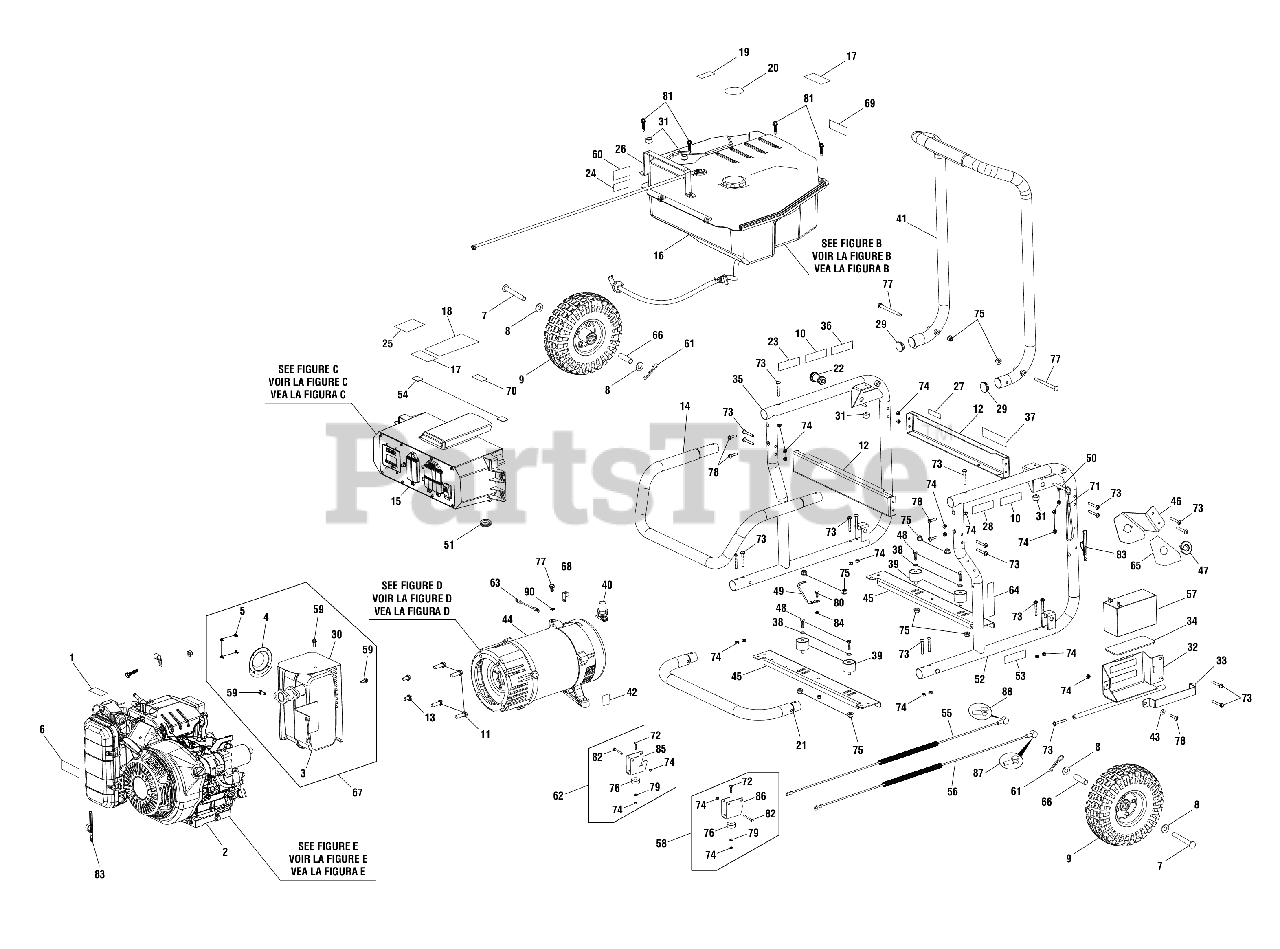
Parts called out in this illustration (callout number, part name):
1	Choke Label
2	Engine
3	Muffler w/Brackets
4	Spark Arrester Screen
5	Screw (8-32 x 3/8 in., Pan Hd.)
6	EMC label
8	Washer (1/2 in.)
9	Wheel (10 in. x 3 in.)
10	LABEL, ZERO GRAVITY
11	Bolt, Wiz (3/8-18 x 1-1/4 in.)
12	CROSSMEMBER, FUEL TANK
13	Bolt (5/16-24 x 0.6 in., Hex Hd.)
14	FRONT TUBE, TOP RIDGID
15	Control Panel Assembly (See Figure C)
16	Fuel Tank (See Figure B)
17	LABEL, LOGO RIDGID
18	LABEL, PERFORMANCE 7000 WATT
19	No E85 Label
20	Fuel Stabilizer Label
21	FRONT TUBE, BOTTOM
22	RELEASE PIN CM80034
23	Fire Distance Label (Eng/Sp)
24	Hot Surface and Exhaust Label
25	CPSC Danger Label
26	BRACKET, WRAPPER BOX SUPPORT
27	LABEL, CLICK/CALL/SCAN RIDGID
28	Risk of Fire Danger Label
29	End Cap (Handle)
30	Heat Shield
31	Rubber Bumper
32	BATTERY BOX ASSEMBLY, SMALL
33	Battery Hold Down Bracket Assembly
34	Gasket (Battery Hold Down Bracket)
35	RIGHT FRAME ASSEMBLY
36	Quick Release Pin Label
37	Ground Warning Label
38	Lock Washer (OD14.8 x ID8.5 x 1t)
39	Isolator Generation 7
40	Rubber Sleeve
41	HANDLE ASSY W/ CAPS
42	Ground Label Icon
43	Data Label
44	ASSEMBLY, GENHEAD 7.0kW, Al, <6% THD
45	CROSSMEMBER, ENGINE/GENHEAD
46	BRACKET, FUEL VALVE, RIDGID
47	Fuel Valve Bezel
48	Bolt (M8 x 1.25 in., Hex Hd.)
49	Ground Wire Assembly
50	Release Pin (5/16 x 2 in.)
51	GROMMET 16mm ID
52	LEFT FRAME ASSEMBLY
53	Engine Lubricant Label
54	RUBBER ISOLATOR
55	BATTERY CABLE RED
56	Battery Cable (Black 390 mm)
57	Battery Bracket
58	LEFT FOOT ASSEMBLY, BLACK
59	Bolt (M6 x 9 mm, Hex Flange Hd.)
60	UL Fire Warning Label Spark Arrestor)
61	Superseded by 310739009
63	WIRE, BONDING 95MM 10AWG
64	LABEL, ENGINE START RD HONDA
65	LABEL, FUEL VALVE ON/OFF
66	Axle Spacer
67	Muffler Assembly
68	Ground Lug (1/4-20)
69	Warning Label
70	LABEL, STARTING WATTS RDCA7000
71	BUNGE CORD RETAINER
72	Superseded by 660224019
73	Bolt (M6 x 42 mm, T30 Torx Hex Hd.)..
74	Lock Nut (M6 x 1 mm)
75	Flange Lock Nut (M8 x 1.25 mm)
76	Rubber Wear Pad
77	Handle Pivot Bolt (M8 x 98 mm, Flat Hd.)
78	Bolt (M6 x 25 mm,T30 Torx Pan Hd.)
79	Washer (OD17 x ID6.4 x 1.6t)
80	Screw (M6 x 16 mm, Hex Hd.)
81	Screw (1/4-14 x 1.25 in., Hex Flange Hd.)
82	Bolt (M6 x 25 mm, Hex Hd.)
83	J Clamp (1/2 in.)
84	Star Washer (M6)
85	FOOT, RIGHT
86	FOOT, LEFT
87	Rubber Battery Cable Boot (Black)
88	Rubber Battery Cable Boot (Red)
